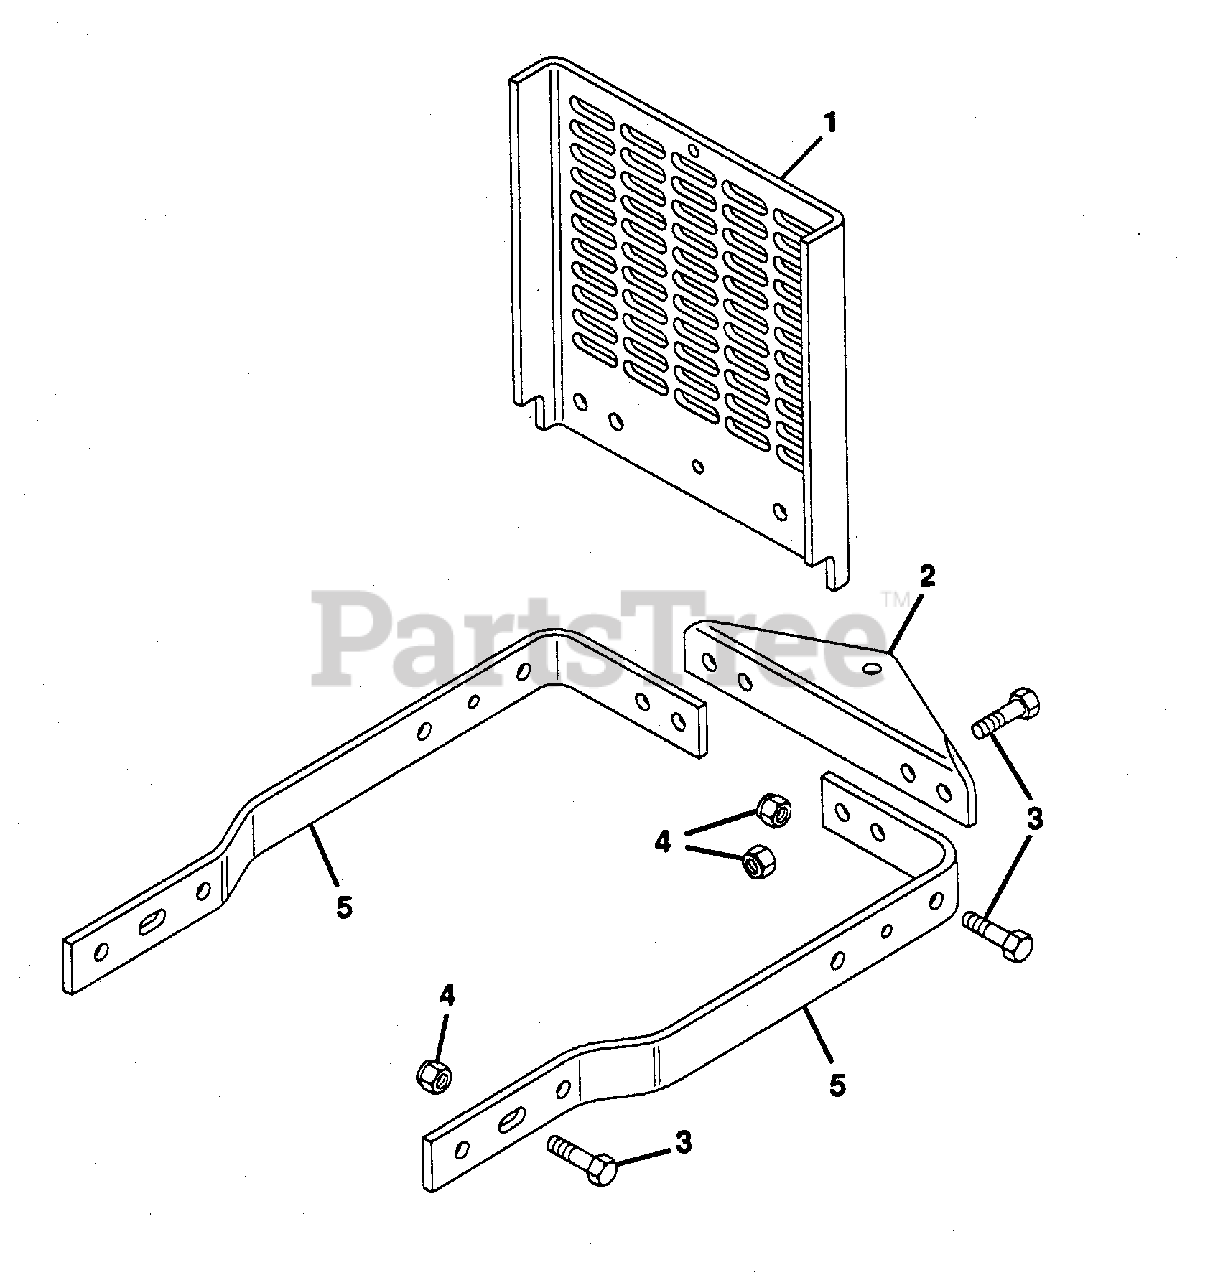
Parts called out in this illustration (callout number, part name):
1	GUARD, ENGINE
2	PLATE, HITCH
3	BOLT, HEX 1/2-13X1.75
4	NUT, LOCK 1/2-13
5	ARM, REAR HITCH
